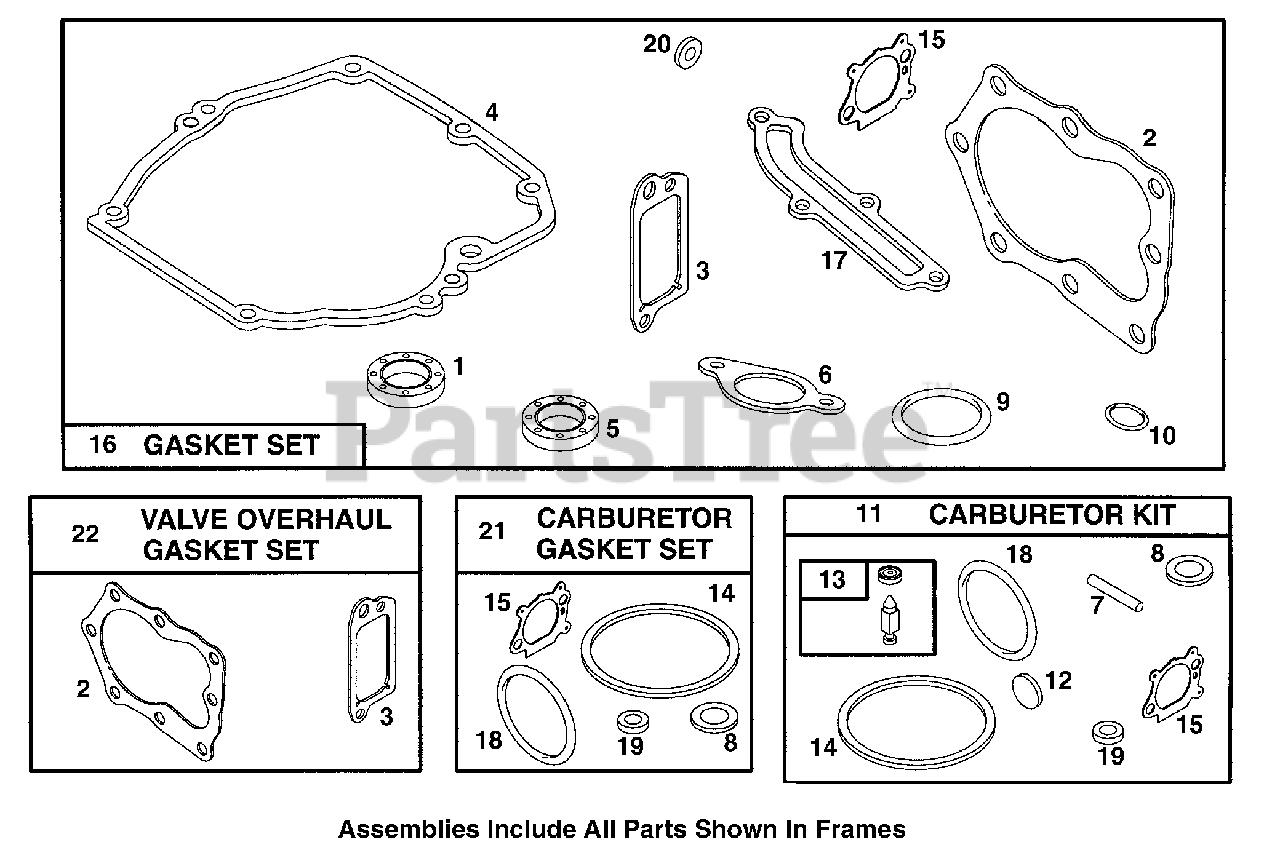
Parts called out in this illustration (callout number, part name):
1	Oil Seal
2	Cylinder Head Gasket
3	Breather Gasket
4	Crankcase Gasket
5	Oil Seal
6	Intake Gasket
7	Float Hinge Pin
8	Bowl Washer
9	O-Ring Seal
10	O-Ring Seal
11	Carburetor Kit
12	Welch Plug
13	Needle/Seat Kit
14	Bowl Gasket
15	Air Cleaner Gasket
16	Gasket Set
17	Breather Passage Gasket
18	Intake Manifold Seal
20	Spacer
21	Carburetor Gasket Set
22	Valve Overhaul Gasket Set
